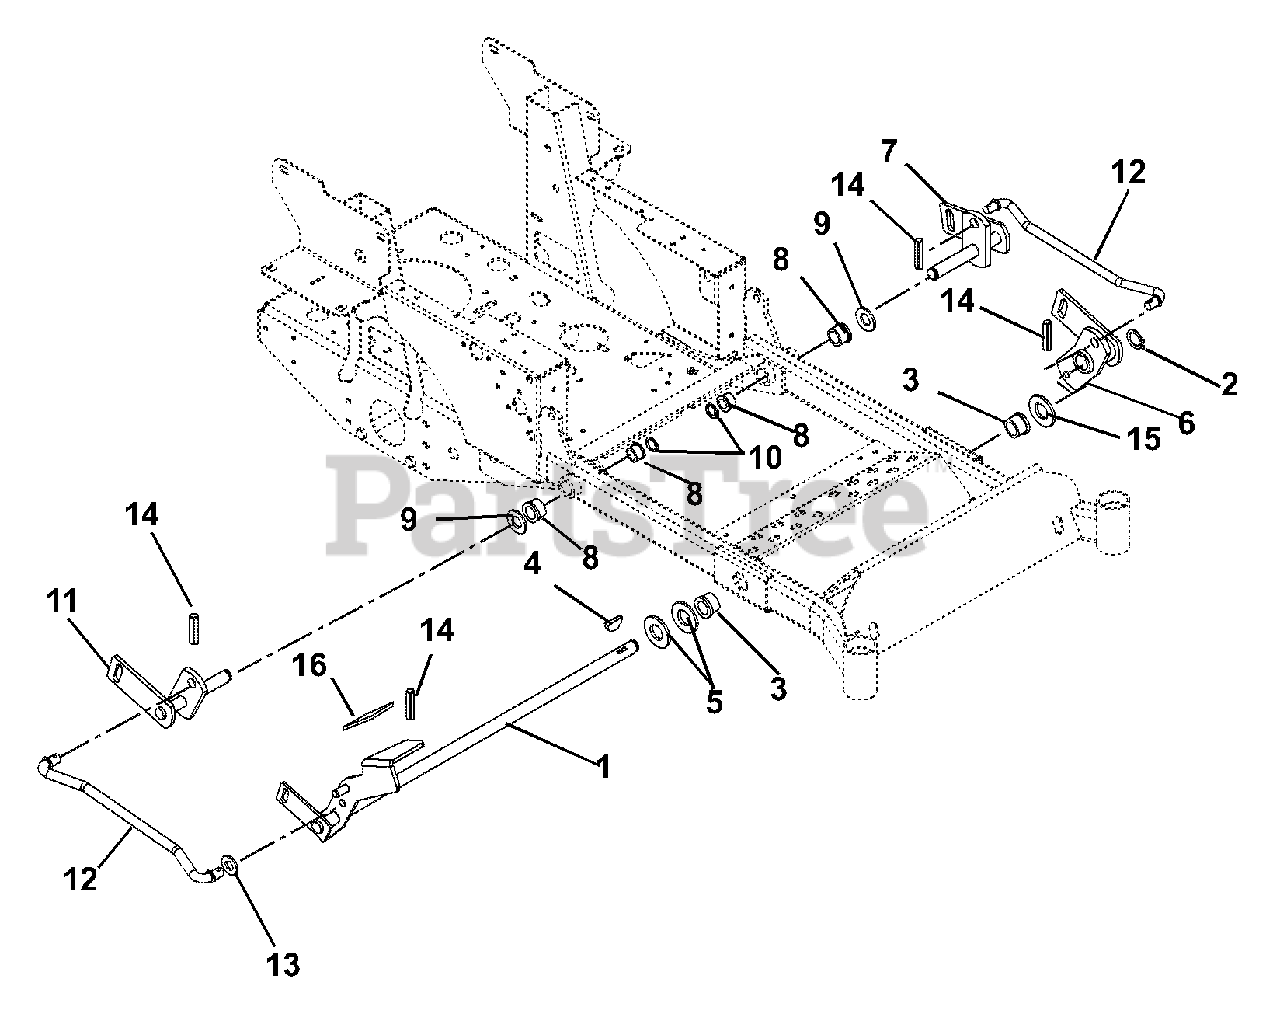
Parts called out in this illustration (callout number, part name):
1	Weldment, Mechanical Deck Lift
2	Ring, Retaining External 1.00 x .078
3	Bushing, Flange Nylon 1.020 x 1.385 x .75 x 1.75
4	Key, Woodruff .25 x 1.00
5	Washer, Flat Steel 1.062 x 2.0 x .134
6	Weldment, Left Hand Mower Lift Arm
7	Weldment, Left Hand Rear Mower Lift Arm
8	Bushing, Flange Nylon .762 x 1.0 x .580 x 1.48
9	Washer, Hardened Steel .758 x 1.23 x .031
10	Ring, Retaining External .689 x .077
11	Weldment, Right Hand Rear Mower Lift Arm
12	Rod, Lift Assist
13	Washer, Flat Steel .630 x 1.25 x .062
14	Pin, Roll .25 x 1.25 Stainless Steel
15	Washer, Hardened Thrust 1.00 x 1.55 x .03
16	Grip, Pedal
